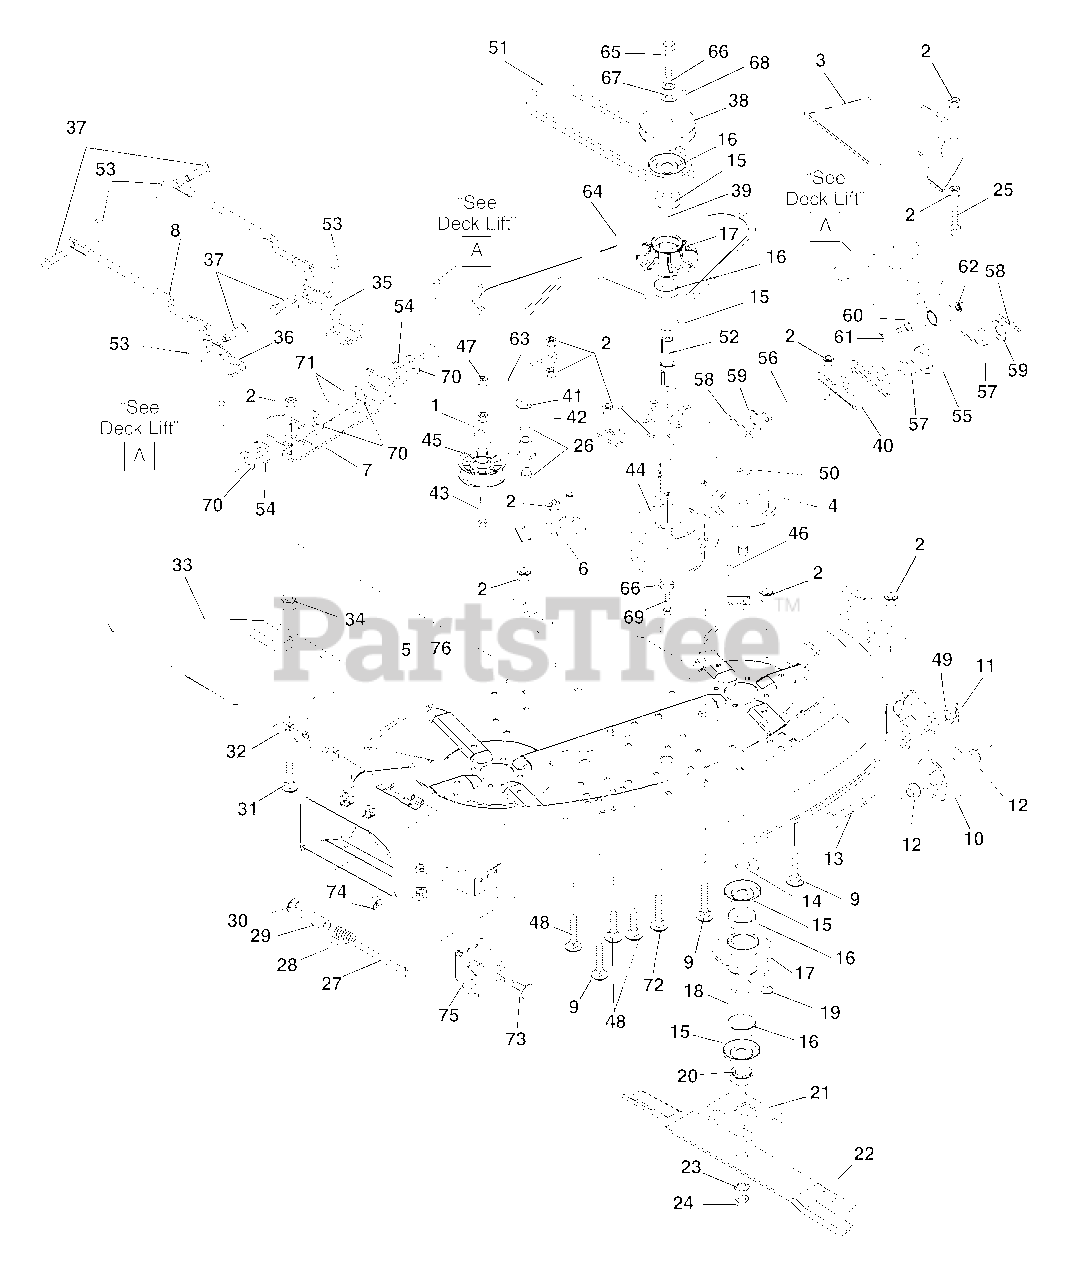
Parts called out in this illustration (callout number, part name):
1	Weldment, Idler
2	Nut, Locking Top Flange .38-16
3	Cover, 40" Deck Sheave
4	Sheave, Left Spindle
4	Sheave, Right Spindle
5	Deck, 40"
6	Bracket, Idler Mount
7	Bracket, Rear Hanger
8	Link, Stabilizer 40" Deck
9	Bolt, Round Head Square Neck .38-16 x 1.00 Grade 55
10	Roller
11	Pin, Hair Internal .08 x .18 x 1.18
12	Bushing, Flange .372 x .500 x .312 x .625
13	Clevis Pin .368/.373 x 3.25
14	Washer, Flat Steel .755 x 1.25 x .125
15	Bearing Slinger
16	Bearing, Ball .750 x 1.781 x .61
17	Spindle Housing
18	Spacer .751 x 1.00 x 1.14
19	Bolt, Round Head Square Neck .38-16 x 1.0 Grade 5
20	Retainer Hub
21	Blade Tray 48
23	Washer, Lock .75 x .188
24	Nut, Jam .75-10
25	Bolt, Hex .38-16 x 1.00 Grade 5
26	Bushing, Flange .500 x .625 x .312 x .75
28	Spring, Torsion .095 x .50 x 1.00
29	Bushing
30	Ring, Retaining External .313 x .025
31	Bolt, Round Head Square Neck .25-20 x .50
32	Hinge Plate
33	40 In Deflector
34	Nut, Locking Flange .25-20 Grade F
35	Bracket, Deck Link Left Hand
36	Bracket, Deck Link Right Hand
37	Pin, Clevis .494 x 1.00
38	Pulley, 40" Deck Input
39	Spacer .75 x 1.00 x 1.14
40	Bracket, Front Hanger
41	Ring, Retaining External .50 x .042
42	Washer, Flat Steel .505 x .880 x .072
43	Bolt, Hex .38-16 x 2.25 Grade 5
44	Electric Clutch/Brake
45	Idler, Flat 3.00 x .38
46	Key, Woodruff .188 x .625 x .31
47	Nut, Locking Center .375-16
48	Bolt, Round Head Square Neck .38-16 x .75 Grade 5
49	Bolt, Round Head Square Neck .31-18 x 1.00
50	Bracket, Spindle Housing Mount
51	Belt, 40" Deck PTO
52	Input Shaft 40" Deck
53	Clip, Spring
54	Slider, Hanger Bracket
55	Link, Front Lift
56	Pivot, Front Lift Lower
57	Bushing, 1.00 x .75 x 1.00
58	Pin, Hair
59	Washer, Flat Steel .75 x 1.47 x .134
60	Bushing, Sleeve .50 x .75 x 1.56
61	Bolt, Round Head Square Neck .50-13 x 2.75
62	Nut, Locking Center Jam .50-13
63	Spring, Tension .095 x .50 x 5.50
64	V-Belt A-Section 12.58 x .48
65	Bolt, Hex .38-16 x 01.00 Grade 8 with Epoxy Patch
66	Washer, Locking .375 x .115 Heavy
67	Washer, Flat Steel .406 x 1.375 x .135
68	Key, Square.187 x .50 x .187 Hardened
69	Bolt, Hex .38-24 x 2.00
70	Washer, Flat Steel .518 x 2.00 x .105
71	Pin, Hair External
72	Bolt, Round Head Square Neck .38-16 x 2.00 Grade 5
73	Bolt-Round Head Square Neck .31-18 x .62
74	Nut, Spin Lock Flange .312-18
75	Roller Clevis
76	Kit, 40" Deck Assembly Service
